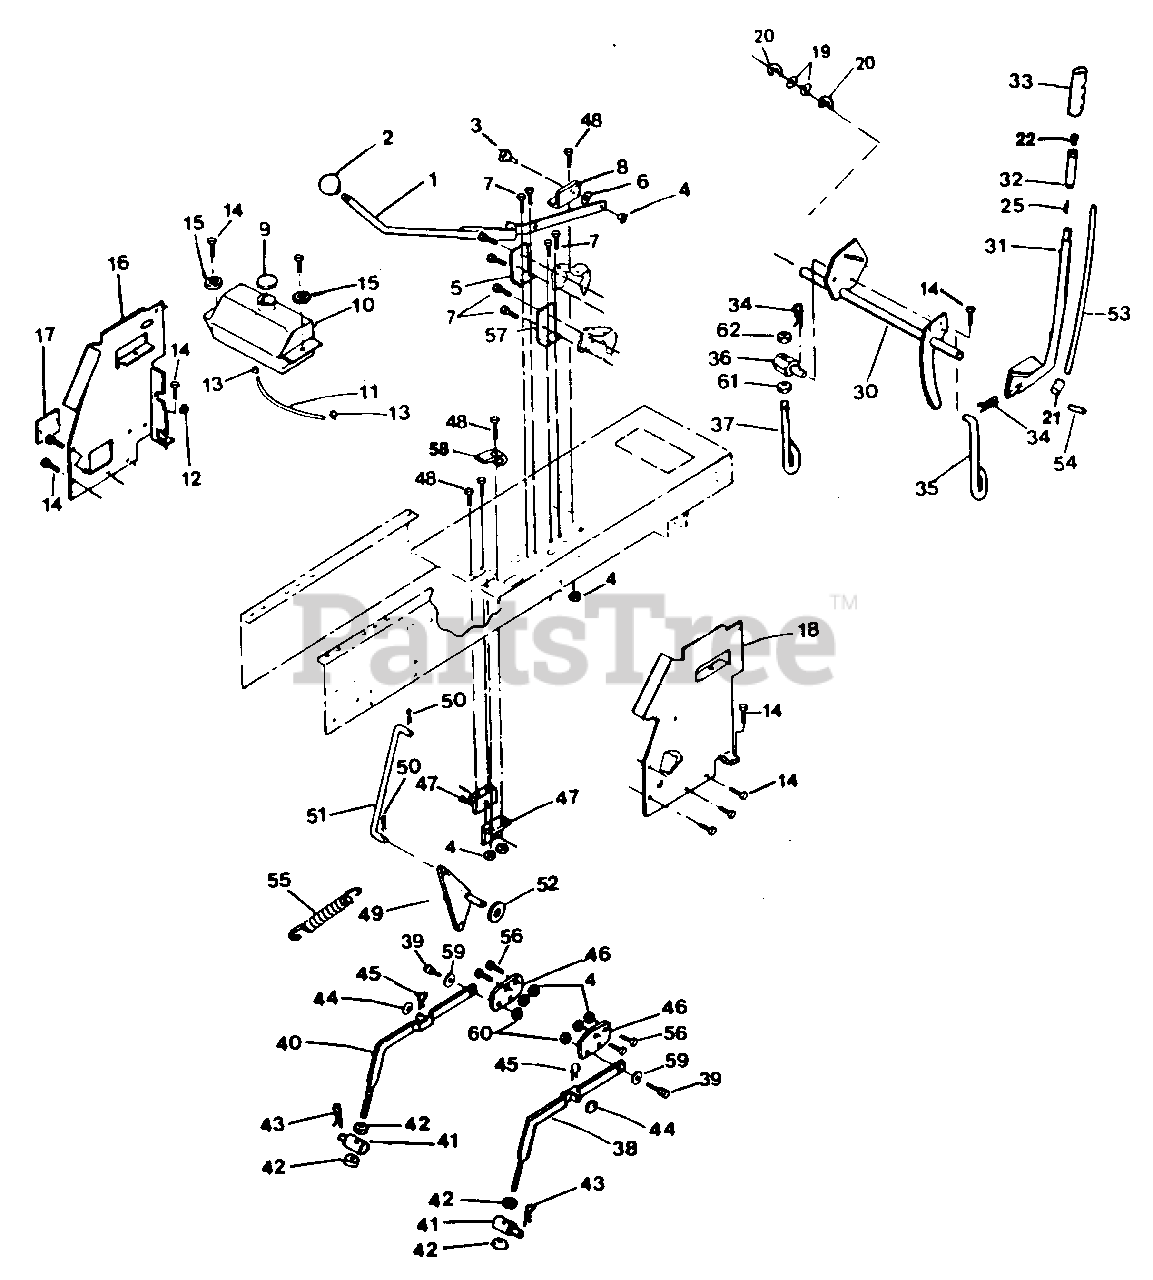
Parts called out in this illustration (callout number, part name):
1	Mower Clutch Lever (AYP part number)
2	Knob (AYP part number)
3	Shoulder Bolt (AYP part number)
4	Crownlock Nut
5	Interlock Switch Bracket (AYP part number)
6	Washer (AYP part number)
7	Tapping Hex Screw (AYP part number)
8	Clutch Support Lever (AYP part number)
9	Fuel Cap (AYP part number)
10	Fuel Tank (AYP part number)
11	Fuel Line (AYP part number)
12	Grommet (AYP part number)
13	Hose Clamp (AYP part number)
14	Thd. Roll. Washer Hd. Hex Screw (AYP part number)
15	Washer (AYP part number)
16	L.H. Dash Panel (AYP part number)
17	Access Cover (AYP part number)
18	R.H. Dash Panel (AYP part number)
19	Washer (AYP part number)
20	E-Ring (AYP part number)
21	Lift Lever Couple (AYP part number)
22	Plunger Button (AYP part number)
25	Spring (AYP part number)
30	Lift Shaft (AYP part number)
31	Assembly Lever (AYP part number)
32	Plunger (AYP part number)
33	Handle Grip (AYP part number)
34	Spring Retainer (AYP part number)
35	Lift Link (AYP part number)
36	Lift Trunnion (AYP part number)
37	Adjustable Lift Link (AYP part number)
38	R.H. Arm Suspension (AYP part number)
39	Shoulder Bolt (AYP part number)
40	L.H. Suspension Arm (AYP part number)
41	Lower Lift Trunnion (AYP part number)
42	Hex Nut 1/2-13 (AYP part number)
43	Spring Retainer (AYP part number)
44	Washer (AYP part number)
45	Spring Retainer (AYP part number)
46	Suspension Bracket (AYP part number)
47	Bellcrank Bracket (AYP part number)
48	Hex Bolt 3/8-16 x 3/4 (AYP part number)
49	Bellcrank Assembly (AYP part number)
50	Cotter Pin (AYP part number)
51	Primary Clutch Rod (AYP part number)
52	Washer (AYP part number)
53	Lift Lever Rod (AYP part number)
54	Groove Pin (AYP part number)
55	Extension Spring (AYP part number)
56	Screw (AYP part number)
57	Switch Bracket (AYP part number)
58	Insulated Clip (AYP part number)
59	Spring Washer (AYP part number)
60	Flange Lock Nut (AYP part number)
61	Jam Hex Nut (AYP part number)
62	Crownlock Nut (AYP part number)
